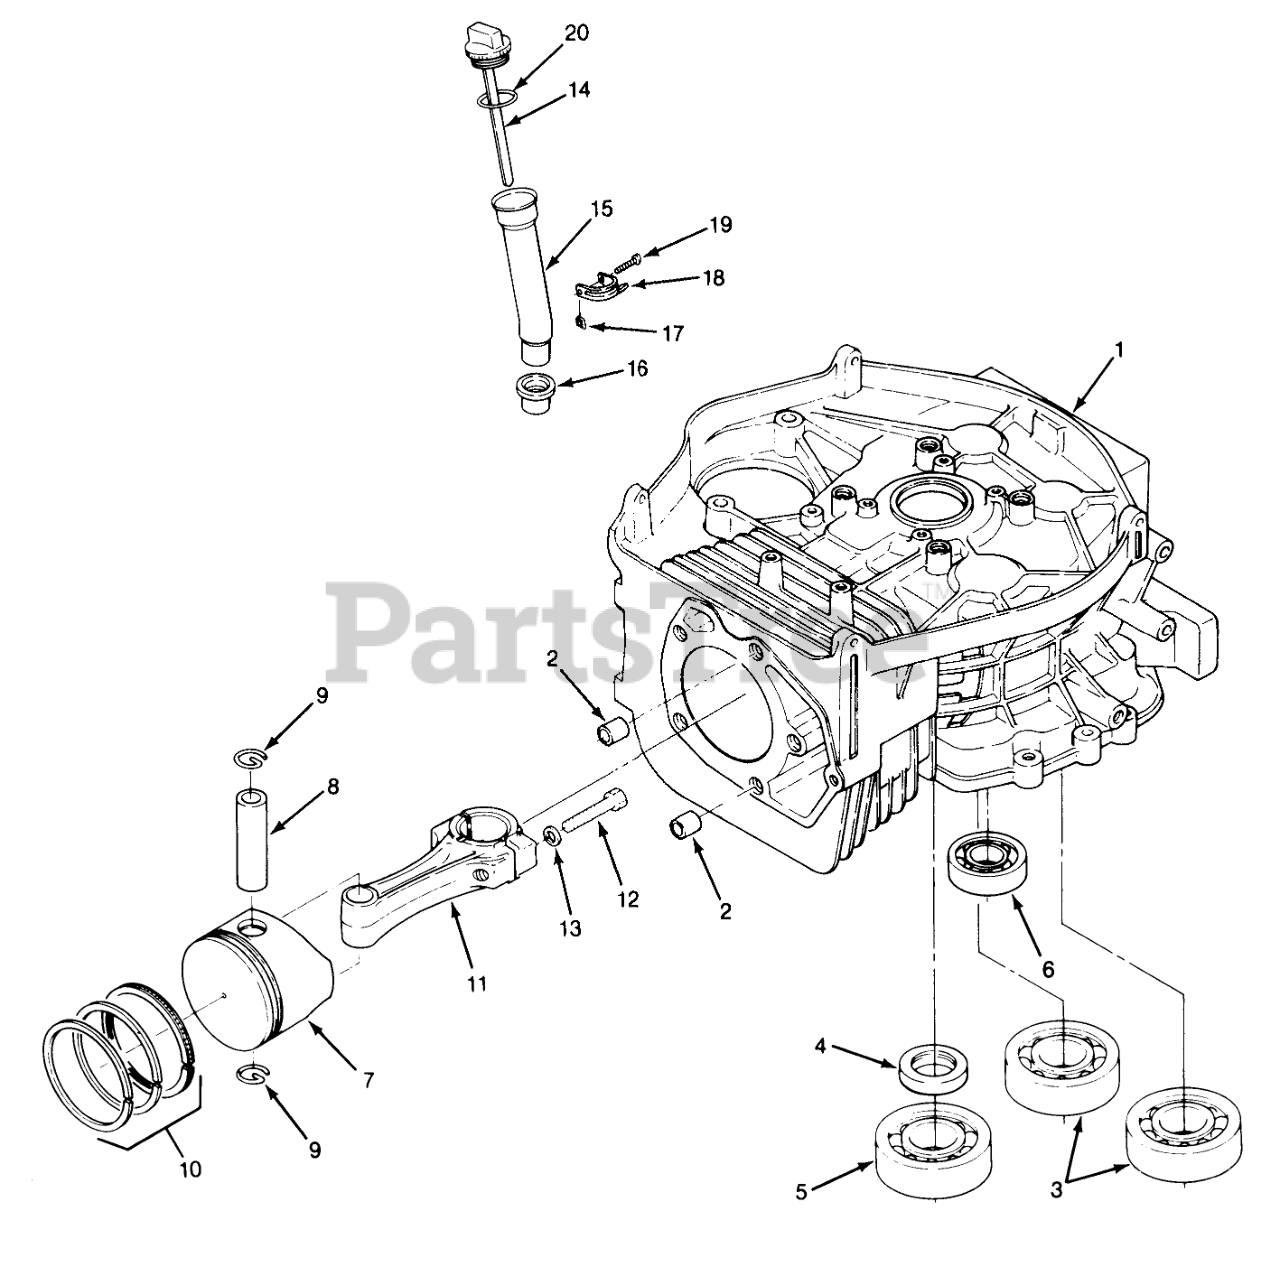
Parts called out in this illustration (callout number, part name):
1	BLOCK-CYLINDER
2	Dowel Pin
3	Ball Bearing
4	SEAL-OIL CRNKSHFT UP
5	BEARING-BALL CRANKSH
6	BEARING-BALL CAMSHFT
7	Kit-Piston (Standard)(Incl. Ref. #8-9)
8	PIN-PISTON
9	RING-RETAINING
10	Piston Ring Set-Standard
11	Kit-Connecting Rod (Standard) (Incl. Ref. #12-13)
12	Bolt
13	WASHER-CONN ROD
14	INDICATOR
16	Seal
17	Nut
18	BRACKET
19	Screw
20	O-Ring
